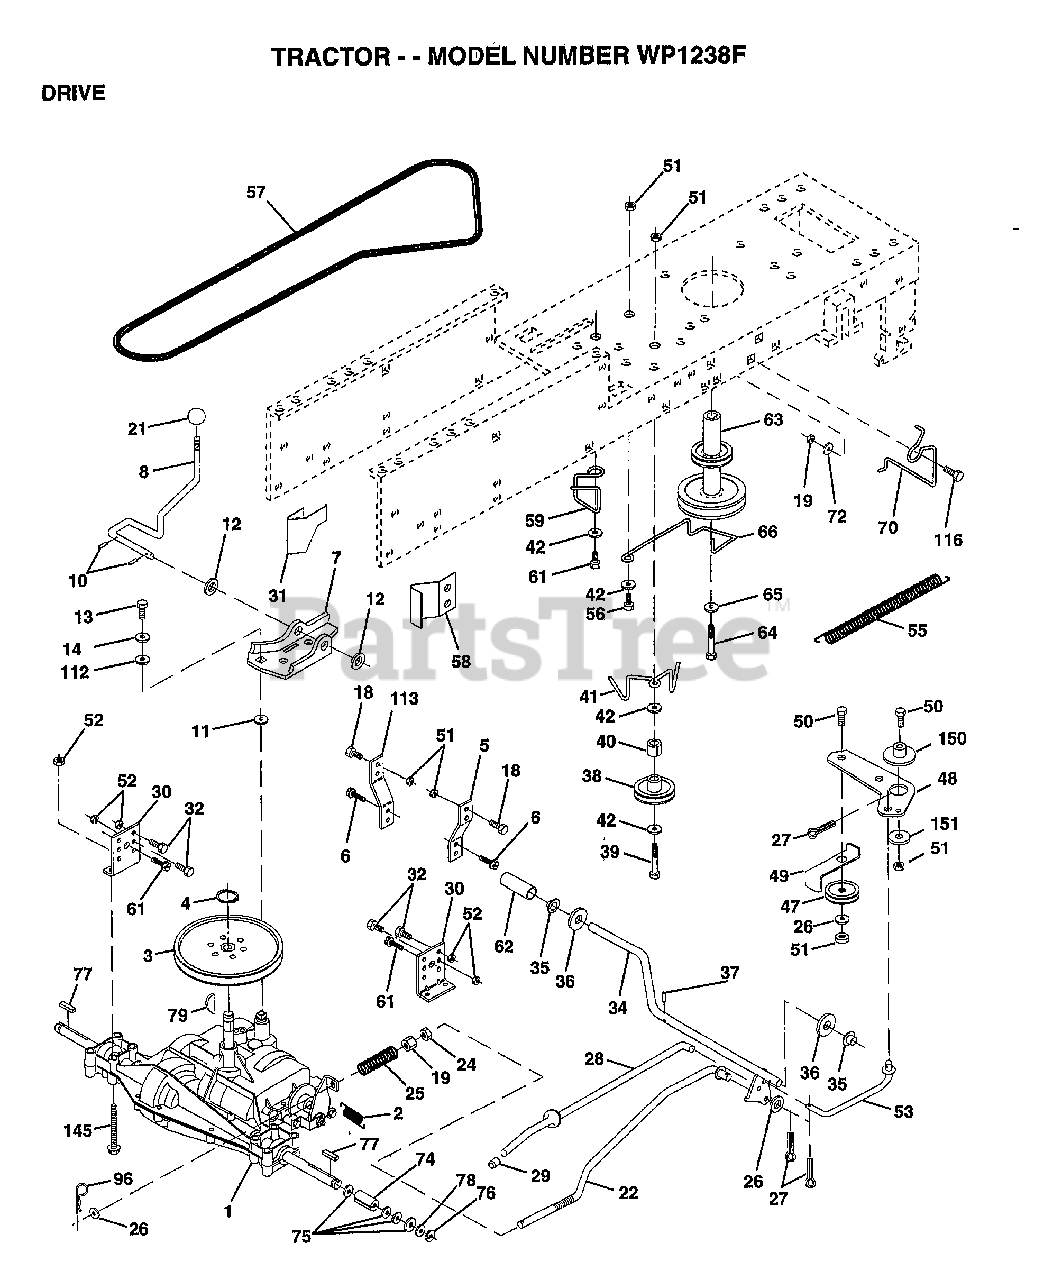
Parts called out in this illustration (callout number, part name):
2	SPRING.BRAKE.RETU
3	PULLEY TRANS
5	STRAP TORQUE
6	SCREW
7	BRKT.SADDLE.SHIFT
8	SHIFT ROD
10	PIN COTTER 1/8
11	WASH-SHFT PLT LT
12	WASHER
13	BOLT.1/4-28.W/PAT
14	LOCKWASHER
18	BOLT
19	NUT
21	KNOB T (1/2-HOLE)
22	BRAKE ROD
24	NUT
25	SPRING ROD LT
26	WASHER
27	COTTER PIN
28	ROD.BRAKE.PARK.LT
29	PLUNGER CAP T
30	TRANSAXLE MTG BKT
31	"KEEPER,BELT LH T"
32	BOLT
34	SHAFT ASM-PEDAL F
35	NYLON BEARING
36	WASHER LT
38	FLAT IDLER PULLEY
39	BOLT
40	SPACER T
41	"KEEPER,BELT.IDLER FLAT"
42	WASHER
48	BELLCRANK.CLUTCH
49	RETAIN BELT
53	"LINK, CLUTCH T"
55	"SPRING, RETURN LT"
58	"KEEPER,BELT RH T"
59	KEEPER BELT CNTSP
61	SCREW
62	PEDAL COVER T
63	PULLEY.ENGINE
64	BOLT
65	LOCKWASHER
66	KEEPER-BELT
70	KEEPER BELT ENG
72	WASHER
74	SPACER AXLE
75	WASHER
76	E-RING LT
77	SQUARE KEY
78	WASHER
96	RETAINER M
112	WASHER LT
113	"STRAP,TORQUE"
116	BOLT RDHD 3/8-16
145	BOLT.HEX.FLGHD
150	BUSHING.BELLCRANK.GRD.DR
151	WASHER
